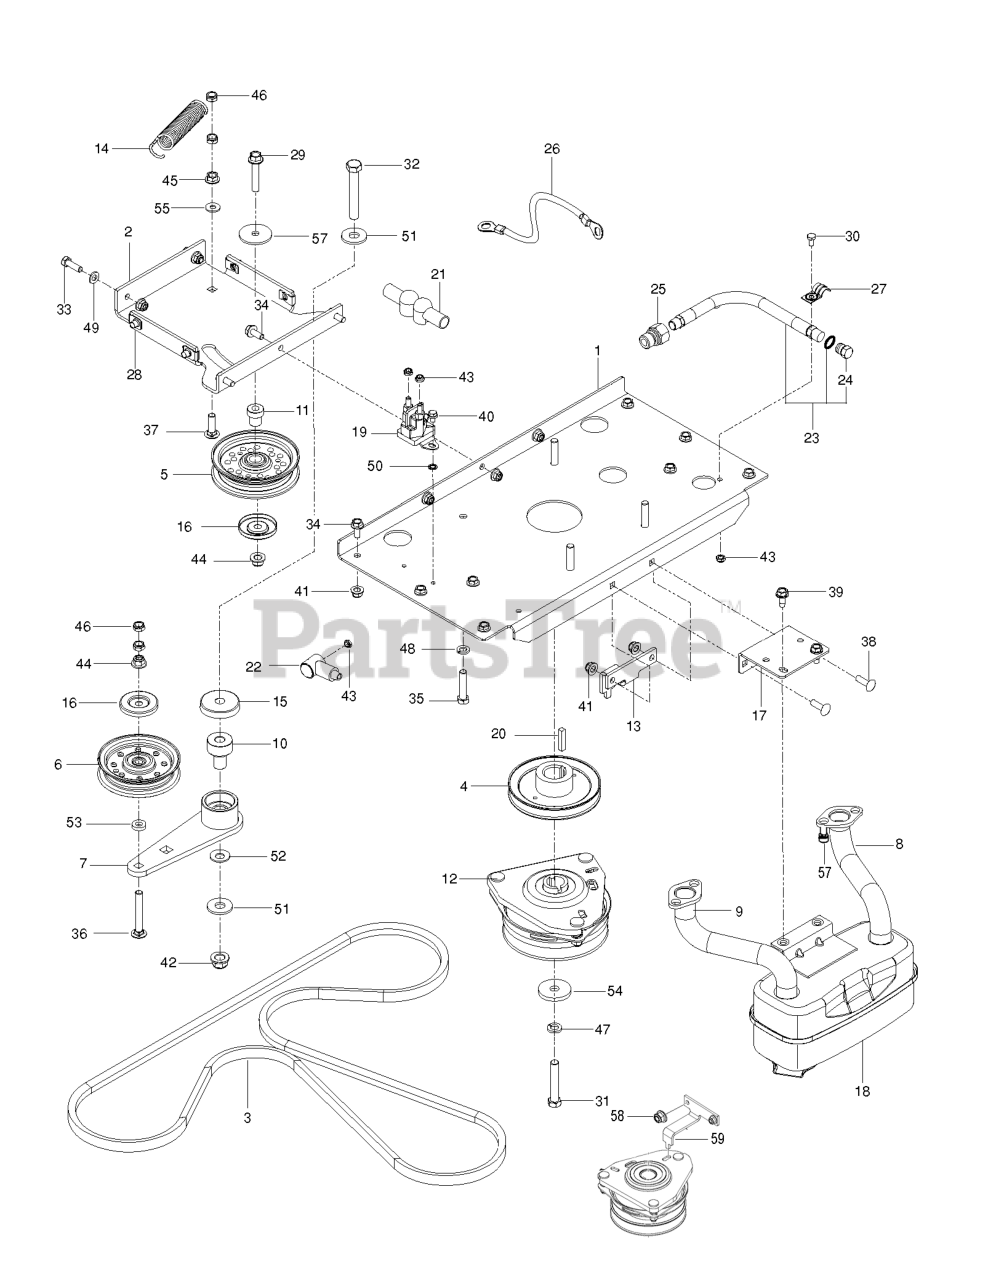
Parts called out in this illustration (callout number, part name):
1	PLATE.PNT.ENGINE.E-DIP
2	PLATE.PNT.IDLER.SUPPORT.E-DIP
3	BELT, HYDRO, 3400
4	PULLEY.DRIVE.XMSN
5	IDLER PULLEY
6	PULLEY.IDLER.FLAT.46.PR.DR.
7	ARM, IDLER, STEEL, W/BGS
8	TUBE.EXHAUST.RH.FR961/FR730
8	PIPE.EXHAUST.RH.CV18/20
9	TUBE.EXHAUST.LH.FR961/FR730
9	PIPE.EXHAUST.LH.CV18/20
10	PIVOT, BEARING
11	PIVOT, IDLER
12	CLUTCH MZ ZTR GT.48/54"1.125"
13	BRACKET.CLUTCH.STOP.PNTX431
14	SPRING, PUMP
15	SHIELD, DUST
16	DUST SHIELD
17	BRKT, MUFFLER, BLK
18	MUFFLER ASM TWIN
19	Solenoids
19	SOLENOID.W/BRASS.PLUNGER
20	KEY, 1/4 SQ X 1 1/4
22	TERMINAL COVER
23	HOSE.ASSEMBLY.OIL.DRAIN
24	PLUG OIL DRAIN
25	ADAPTER, OIL DRAIN
26	CABLE POSITIVE
28	U-CLIP 5/16-18 NUT RETAINER
29	HHFS 3/8-16 X 2.0 GD 5
30	BOLT
30	Screws
30	HCS 1/4-20.
31	Bolts
31	CLUTCH BOLT7/16-20X2.5 GR596HR
32	HCS 1/2-13 X 3-1/4 GD 5 ZD
32	HCS 1/2C X 3 1/4
33	HCS 5/16C X 1
33	BOLT.FIN.HEX.5/16-18UNC X 1.00
34	HHFS 5/16-18 X 3/4
34	Bolts
35	SCREW 3/8-16X1
35	HCS 3/8-16X1.GRD.5.ZD
35	Bolts
36	RHSNB 3/8-16 X 2.75
36	BOLT
37	RHSNB 3/8-16 X 1-1/4
37	BOLT.3/8-14X1.25
38	Bolts
38	RHSSNB 5/16C X 1.0
38	BOLT CRT
39	BOLT 5/16-18 X 3/4
39	Bolts
39	SCREW.THDROL.5/16-18X3/4.TTY
40	Screws
40	HWST 1/4C X 3/8
40	RP_SCREW.1/4-20X3/8
41	5/16-18 NYLOC FLANGE NUT
42	NUT, 1/2-13 HEX FLG NYLOC ZD
43	JAM NUT 1/4C (2 2 PW01)
43	Hardware
44	NUT 3/8-16 HEX FLG NYLOC ZD
45	NUT 3/8C WHIZ
46	NUT HEX 3/8-16 NYLON, THIN
47	SLW 3/8 STD
47	Washers
48	Washers
48	WASHER 7/16 LOCK
49	FLAT WASHER 5/16 SAE
49	WASHER
50	WASHER 1/4 INT TOOTH
51	WASHER.9/16 X 1 3/8 X 12 GA.
51	WASH USS FLAT 1/2
52	CONTACT BELLSPR 1/2
53	WASHER 3/8 X 3/4 X .187 TK
54	SPINDLE WASHER
54	Washers
55	RP WASHER 3/8 FLAT
56	WASHER, 3/8 SPEC
57	SCREW.SOCKET HD.5/16-1
58	NUT HEXAGON FLANGE 5/16-18 ST
59	BRACKET.CLUTCH.STOP.PNTX431
